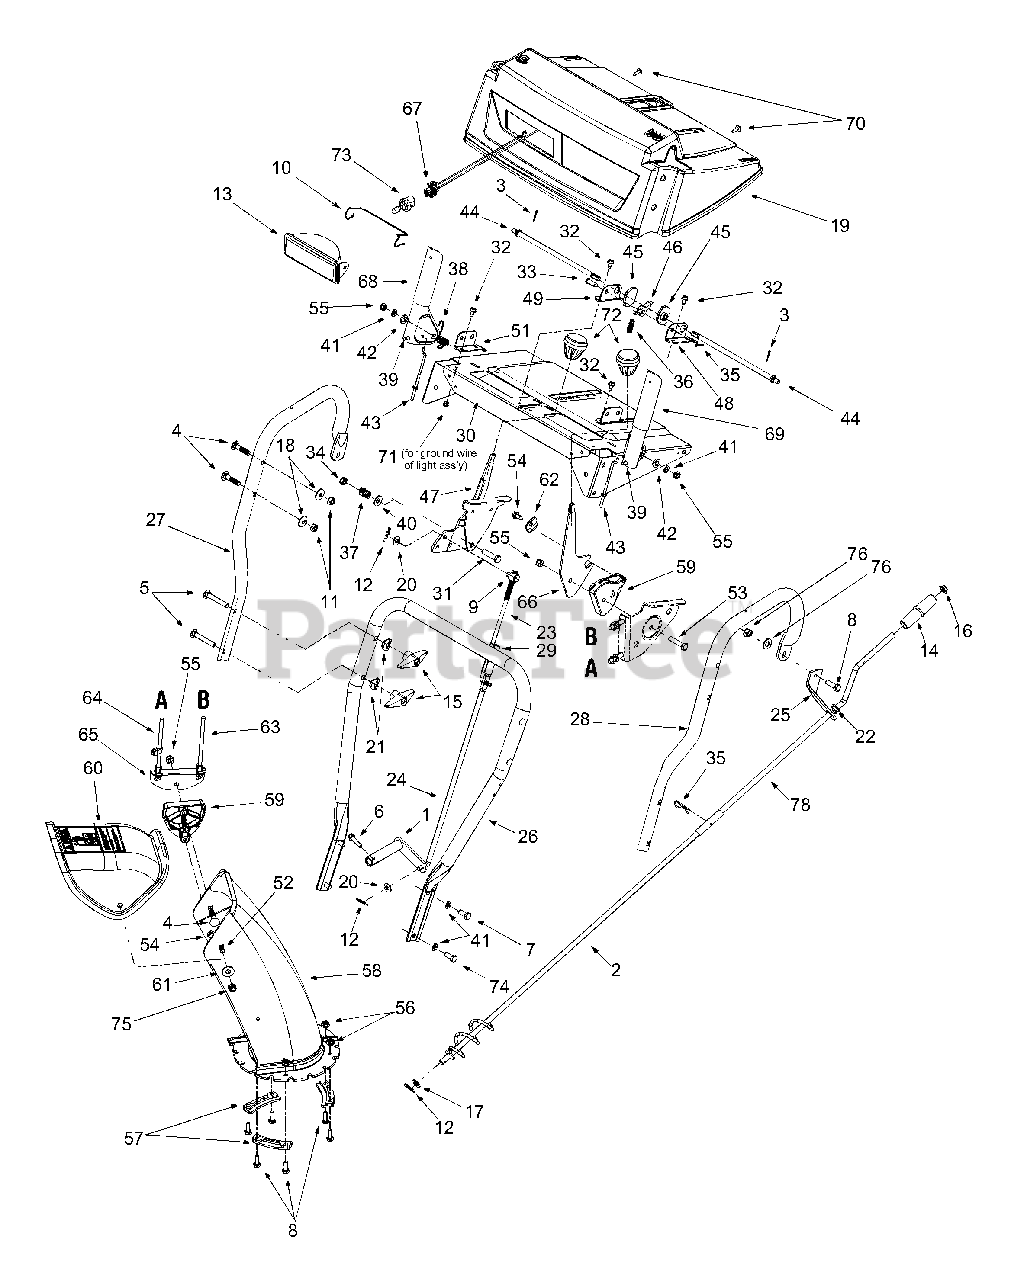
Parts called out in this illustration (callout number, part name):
4	Carriage Bolt, 5/16-18 x 1.75
5	Carriage Bolt, 5/16-18 x 2.25
6	Self Tapping Screw, 1/4-20 x 1
7	Hex Cap Screw, 5/16-18 x 1.0
8	Hex Cap Screw, 1/4-20 x .75
9	Ferrule, 5/16-18 x .312
10	Headlamp Retainer
11	Hex Nut, 5/16-18
12	Internal Cotter Pin
13	Lens Assembly / Lamp Housing
14	Chute Crank Knob
15	Wing Knob, 5/16-18
16	Push Cap, 3/8
17	Flat Washer, .375 x .738 x .063
18	Bell Washer, .34 x .872
19	Handle Panel, Yellow
20	Flat Washer, .344 x .688 x .065
21	Saddle Washer, .32 x .93
22	Plastic Bushing
23	Upper Shift Rod
24	Lower Shift Rod
31	Hex Cap Screw, 3/8-24 x 1.5
32	Self Tapping Screw, 1/4-20 x .5
33	Clevis Pin
34	Jam Nut, 3/8-24
35	Cotter Pin, .072 x 1.0
36	Compression Spring, .36 x 1.0
37	Comp. Spring, .39 x .6 x .88
38	Torsion Spring, .44 x .8
39	Rubber Bumper
40	Bell Washer, .401 x .87 x .063
41	Lock Washer, 5/16
42	Special Washer, .35 x .72 x .13
43	Cable "Z" Fitting
44	Cam Rod
45	Cam Handle Lock
46	Handle Lock Pawl
52	Carriage Bolt, 5/16-18 x .75
53	Hex Cap Screw, 516-18 x 1.5
54	Screw, 1/4-14 x .625
55	Hex Lock Nut, 5/16-18
56	Hex Flange Lock Nut, 1/4-20
57	Lower Chute Flange Keeper
58	Lower Chute
59	Chute Tilt Cable Guide
60	Upper Chute
61	Washer, 5/16
62	Special Washer, .28 x 1.2 x .06
63	Chute Deflector Control
64	Chute Deflector Cable w/ Clip
67	Halogen Light Harness
68	RH Engagement Handle Ass'y
69	LH Engagement Handle Ass'y
70	Special Screw, #10-16 x .625
71	Hex Sems Nut, 1/4-20
72	Plastic Knob
73	Halogen Lamp, 12-volt, 27 Watt
74	Hex Cap Screw, 5/16-18 x .75
75	Hex Nut 5/16-18
76	Bell Washer, .265 x .75 x .062
77	Hex Nut, 1/4-20
